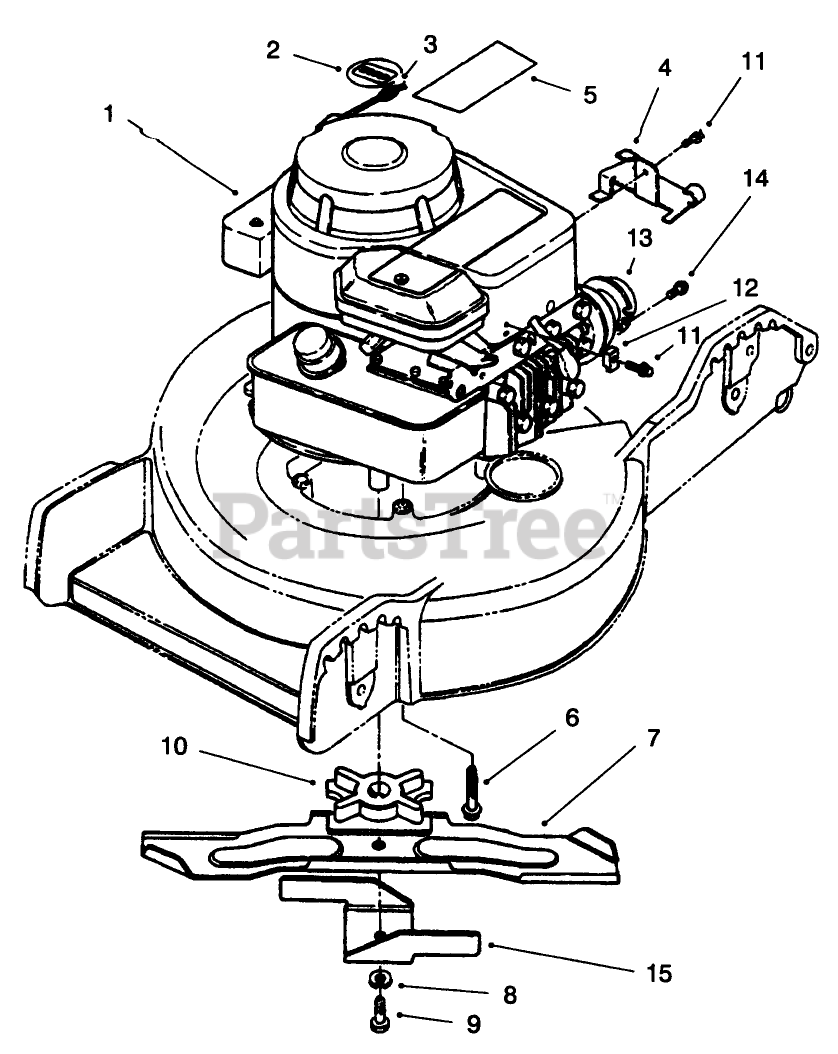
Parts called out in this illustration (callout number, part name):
1	Engine
2	DECAL - ENGINE
3	STOP-ROPE
4	CABLE BRACKET *
5	DECAL - ENGINE
8	WASHER-LOCK
9	SCREW-HH
10	BLADE RETAINER
11	CLAMP SCREW F/W ENGINE
12	CASING CLAMP F/W ENGINE
15	18 ACCELERATOR *
